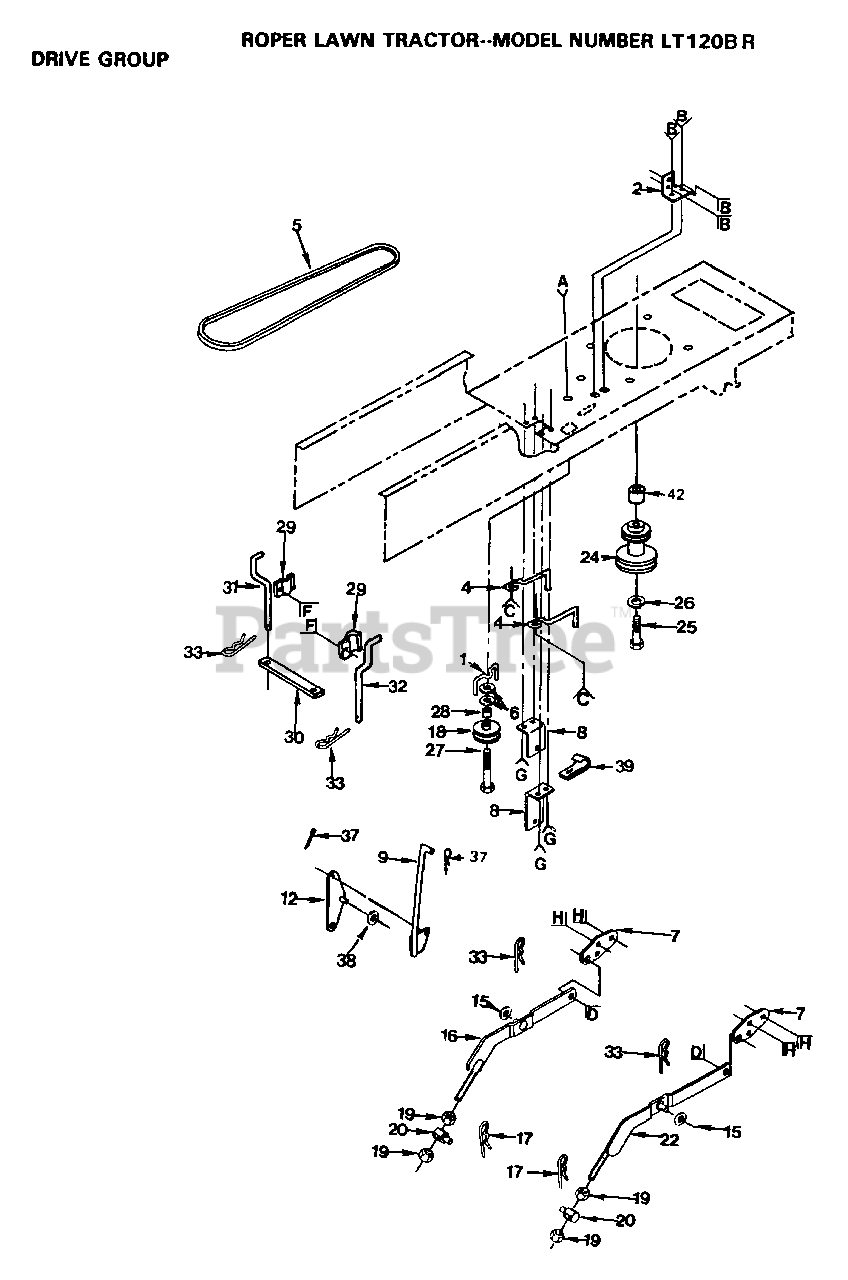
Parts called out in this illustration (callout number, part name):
1	BELT KEEPER LT
2	BRACKET LT
4	"KEEPER,BLT ENG LT"
6	WASHER
7	"BRACKET, SUSPE T"
8	"BRKT,BELLCRAN T"
9	ROD ASSEM YT
12	"T, BELLCRANK"
17	SPRING H
19	NUT
25	BOLT RER
26	LOCKWASHER
27	BOLT
28	SPACER T
29	CLAMP LT
33	SPRING.RETAINER
37	COTTER PIN
38	WASHER
39	INSUL CLIP T
42	SPACER T
